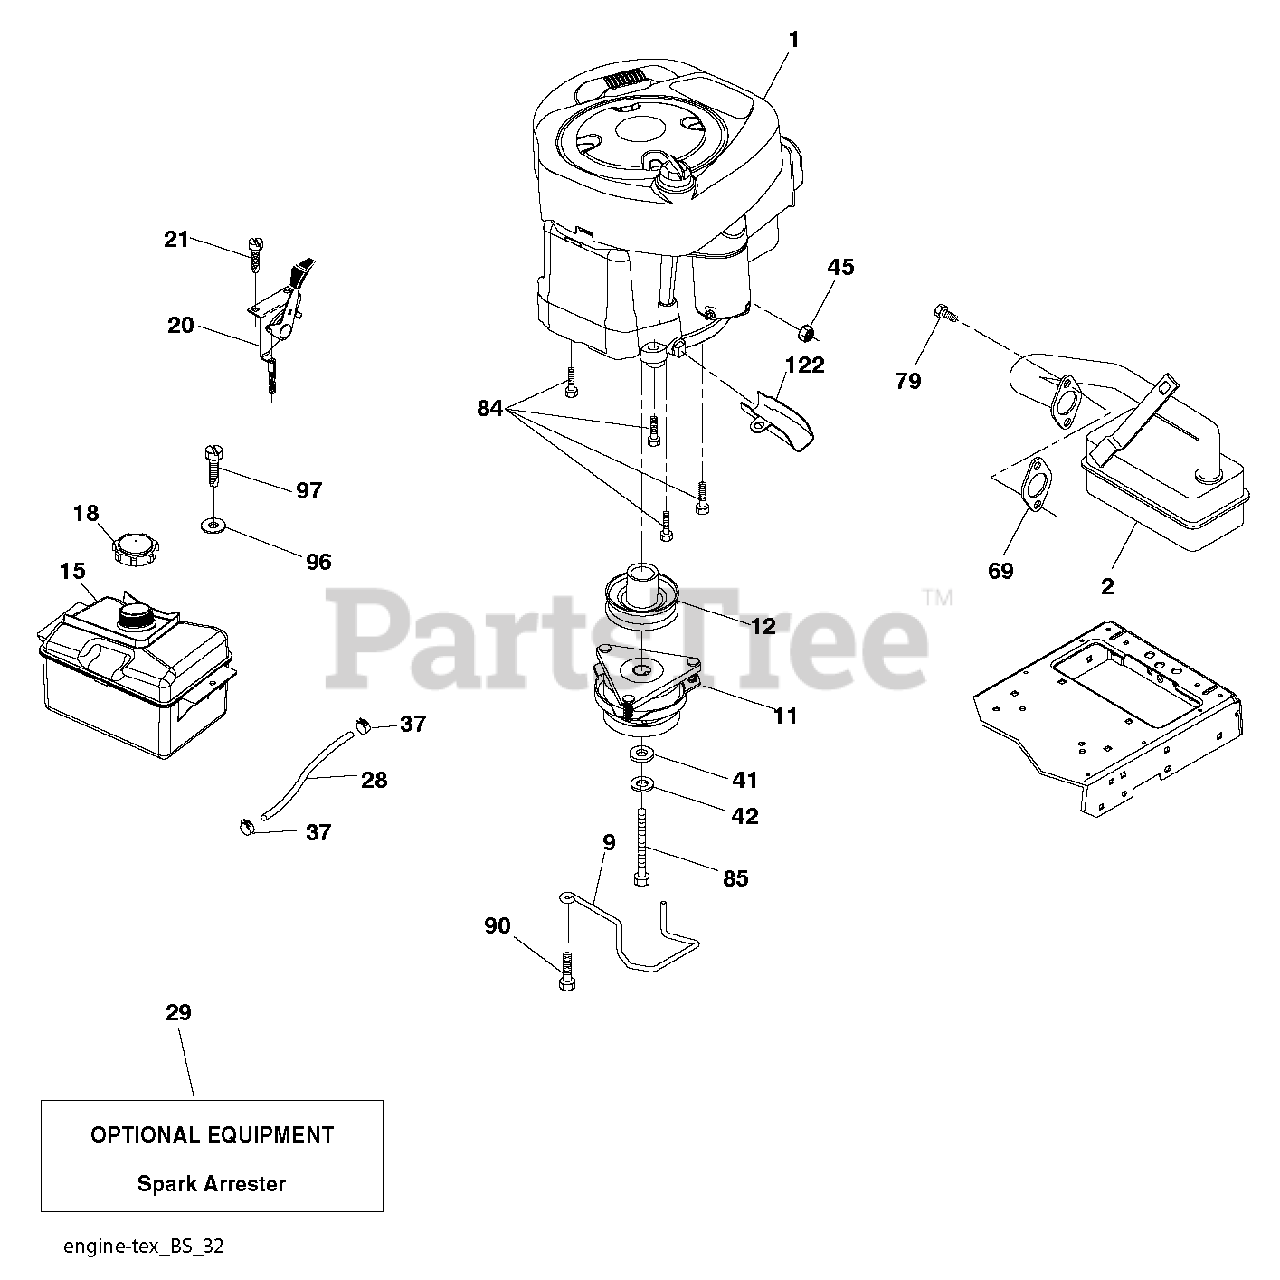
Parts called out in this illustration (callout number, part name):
9	KEEPER.BELT.ENGINE.3.25
11	CLUTCH
12	PULLEY.ASM.ENG.OGURA.3
15	TANK FUEL FRT 1.5 GAL
18	CAP ASM.FUEL.2.25"FR.
20	CONTROL.TH/CK.C.
21	SCREW.#10 X 0.750.BOS THREAD
28	LINE.FUEL.20
29	ARRESTER SPARK (OPTIONAL)
37	HOSE CLAMP
42	LOCKWASHER
45	NUT
69	REPL BY 532 27 22-93
79	SCREW.SOCKET HD.5/16-1
84	SCREW.3/8-16
85	BOLT HEX 7/16-20X4-1/4"
90	SCREW 3/8-16X1
97	SCREW HEXWSHR 1/4-20X3/4
122	EXTENSION DRAIN OIL
